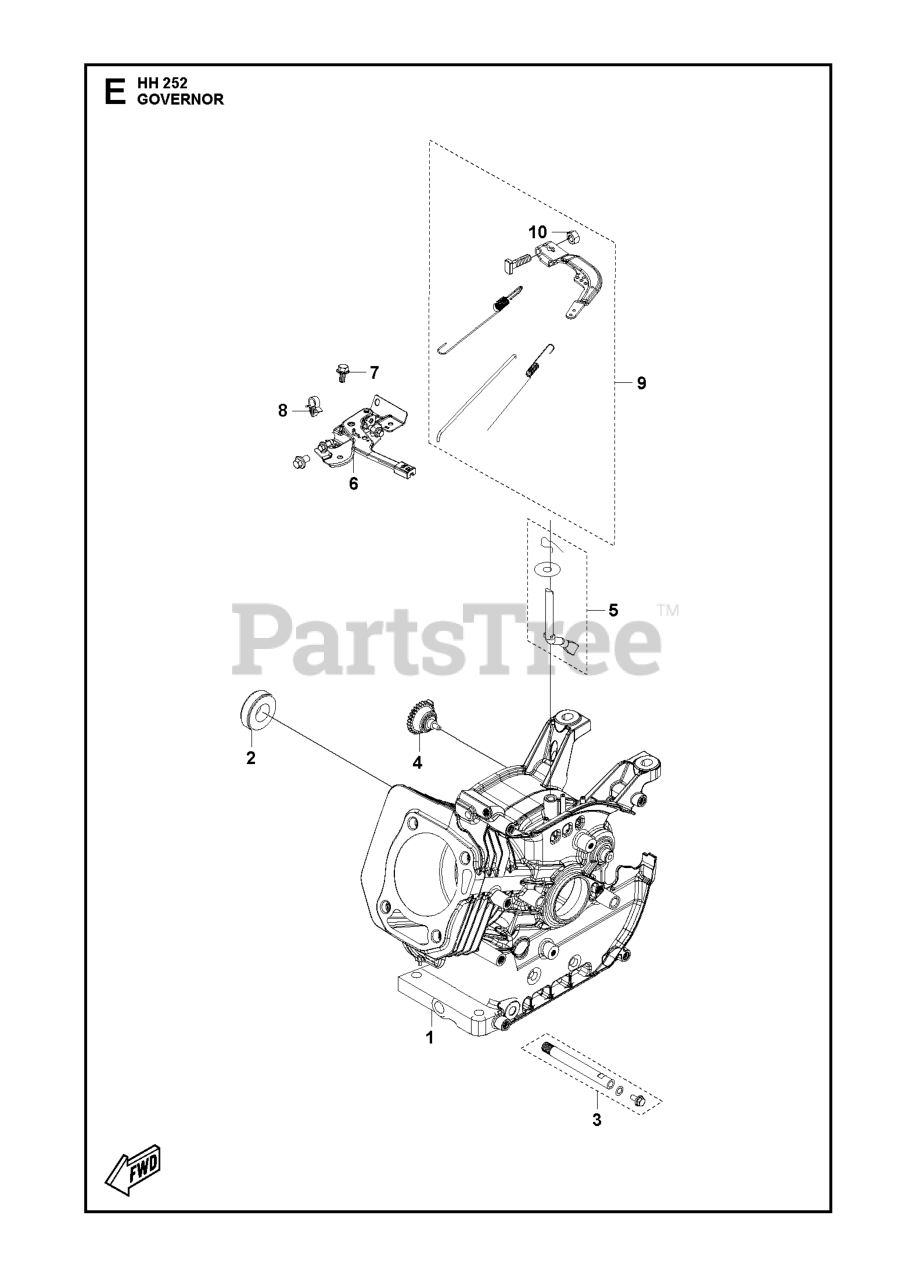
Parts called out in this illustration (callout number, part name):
2	SEAL OIL SEAL
3	PLUG OIL DRAIN PLUG
4	GEAR GOVERNOR GEAR
5	ARM SPEED REGULATING ARM KIT
6	THROTTLE HANDLE
6	SPEED CONTROL SYSTEM
7	BOLT
9	GOVERNOR KIT
10	NUT
